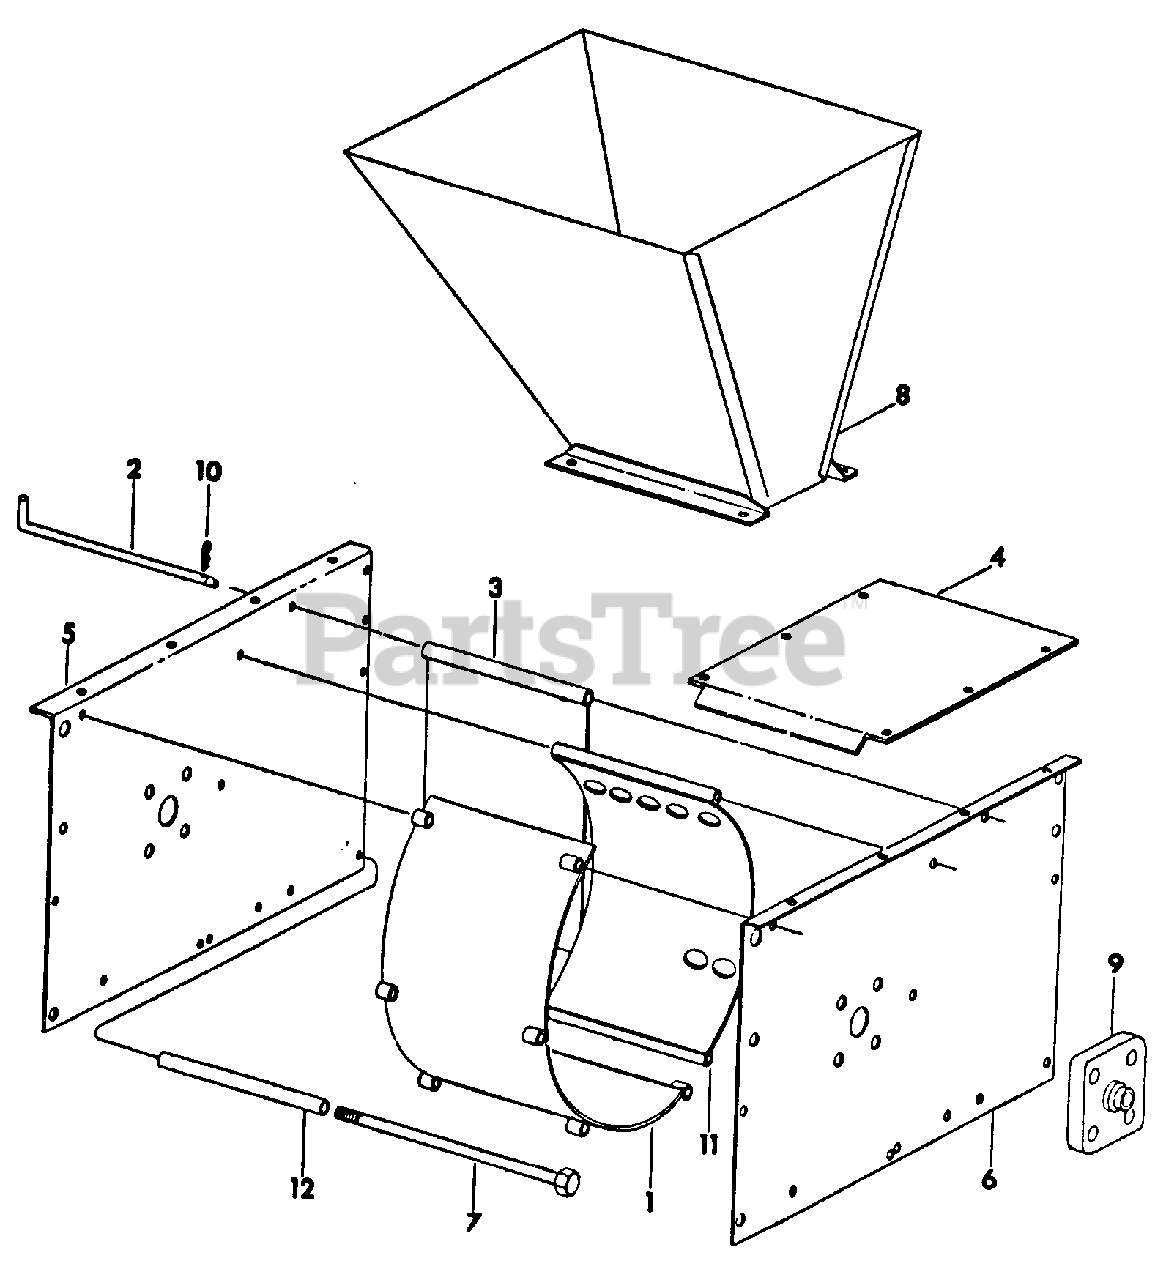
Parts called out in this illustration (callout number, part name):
2	Rod, Screen & Baffle
3	Plate, Baffle
4	Plate, Top
5	Plate, Side LH
6	Plate, Side RH
9	Bearing, Flange
10	Pin, Quick Attachable
11	Screen, 1 In. Perforations
